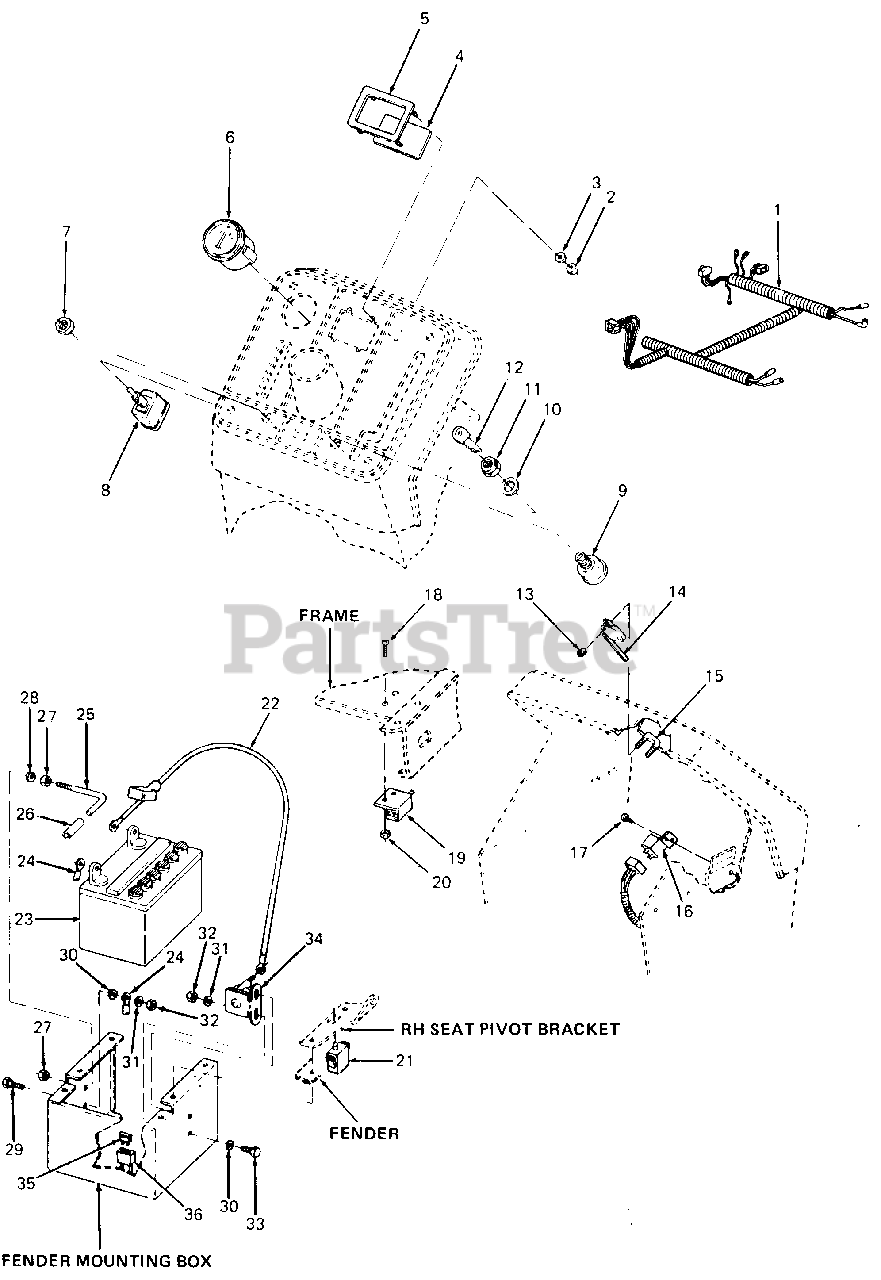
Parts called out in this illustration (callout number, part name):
1	Harness, Wire
2	Nut, Self-Threading Pal
3	Washer, Rubber, .18 X .50 X .06 Thk
4	Label, Indicator
5	Bezel, Light
6	Ammeter
7	Nut, Hex, 1/2-27 X .100 Thk
8	Switch, PTO
9	Switch, Ignition Key
10	Washer, Flat
11	Nut, Ignition Switch
12	Key, Ignition (Set of 2)
13	Nut, Hex Insert Lock, #4-40
14	Switch, Micro
15	Screw, Switch
16	Relay
17	Screw, Pan Hd Tapp, #12 X .50 Lg
18	Screw, #10-24 X .50 Lg
19	Switch, Double Poled Plunger
20	Nut, Hex Center Lock, #10-24
21	Switch, Interlock
22	Wire, Positive Battery
23	Battery, 12 Volt
24	Wire, Ground, 11.5 Lg
25	Pin, Locking
26	Fuel Line, 2 in. Long
27	Nut, Hex, 5/16-24 GR5
28	Washer, Lock, 5/16
29	Screw, Hex Cap, 1/4-20 X .62 Lg GR5
30	Washer, Int Ext Lock, 1/4 X 3/4
31	Washer, Flat, .281 X .73 X .063 Thk
32	Nut, Hex Patch Lock, 1/4-20
33	Screw, Hex Cap, 1/4-20 X .50 Lg GR5
34	Solenoid, 12 Volt
35	Fuse, Auto Type, 20 Amp
36	Fuse Holder
